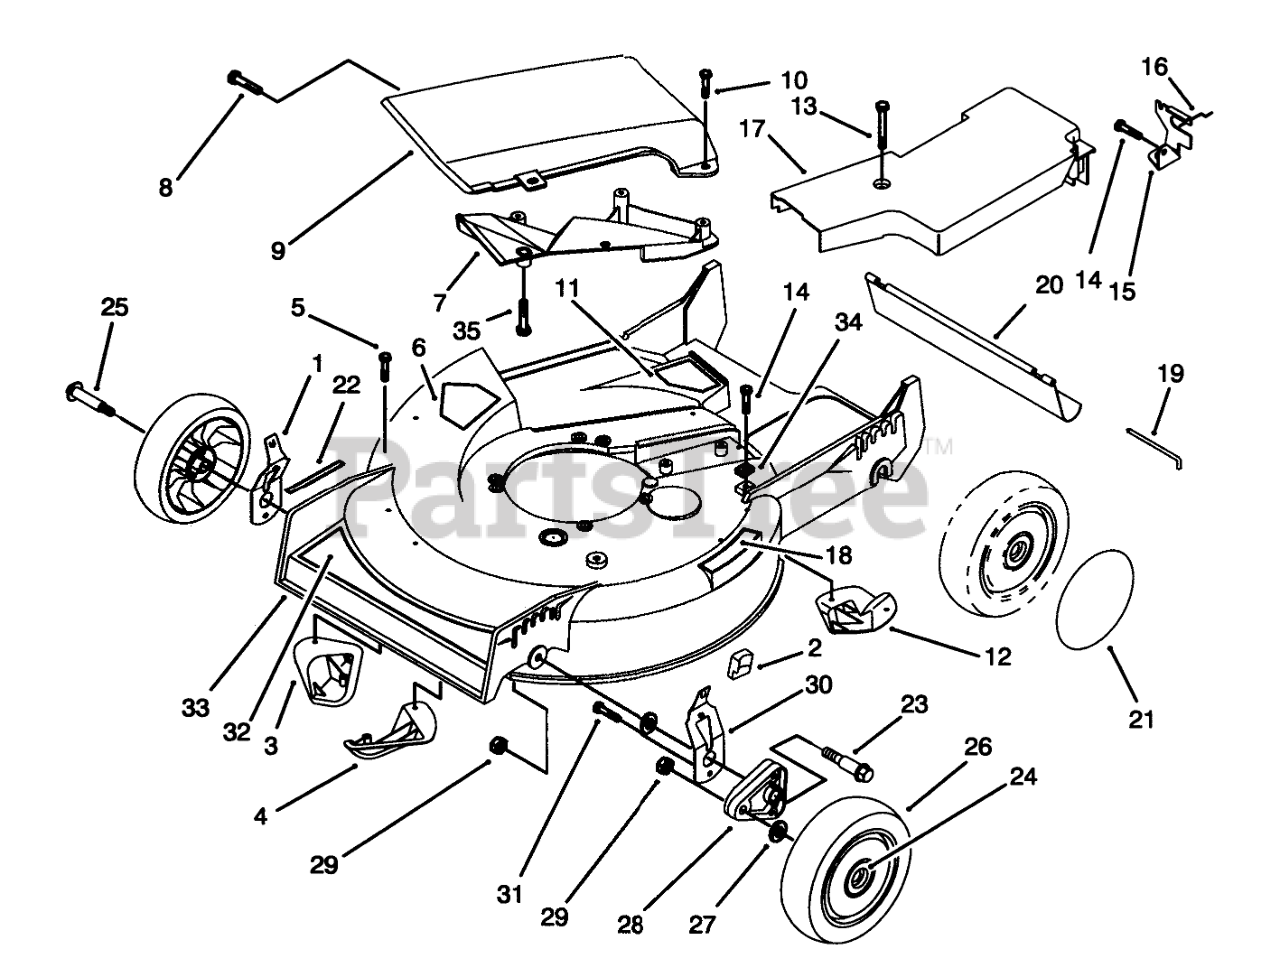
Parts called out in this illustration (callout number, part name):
1	RH SPRING ARM ASM
2	KNOB-ARM
3	KICKER-FRONT
4	KICKER-RH
5	SCREW-PPH
6	DECAL-DANGER
7	Deflector-Recycler
8	SCREW AND WASHER ASM
9	Cover Assembly (Incl. Ref. #7 & 35)
10	SCREW-HWH
11	DECAL - DANGER
12	KICKER-REAR
13	SCREW-HHFTF
14	SCREW-HWHTF
15	Bracket-Adj. Trac
16	RETAINER-CABLE
17	BELT COVER
18	DECAL - STEP PAD INT'L
19	ROD-SHIELD
20	SHIELD-TRAILING
21	WHEEL COVER
22	DECAL - HOC
23	BOLT-SHOULDER
24	BUSHING
25	BOLT-WHEEL
26	Wheel & Tire Assembly (Incl. Ref. #24)
27	WASHER
28	ARM-PIVOT, FRONT
29	NUT-LOCK
30	LH SPRING ARM ASM
31	SCREW-HWH
32	DECAL - DECK
33	Housing Assembly (Incl. Ref.#1,3-6,8,11,12,14,22,pg.1)(Incl. Ref.#5 pg. 3)(Incl. Ref. #30-31 pg.4)
34	CLAMP-CABLE
35	Screw-Plastite
